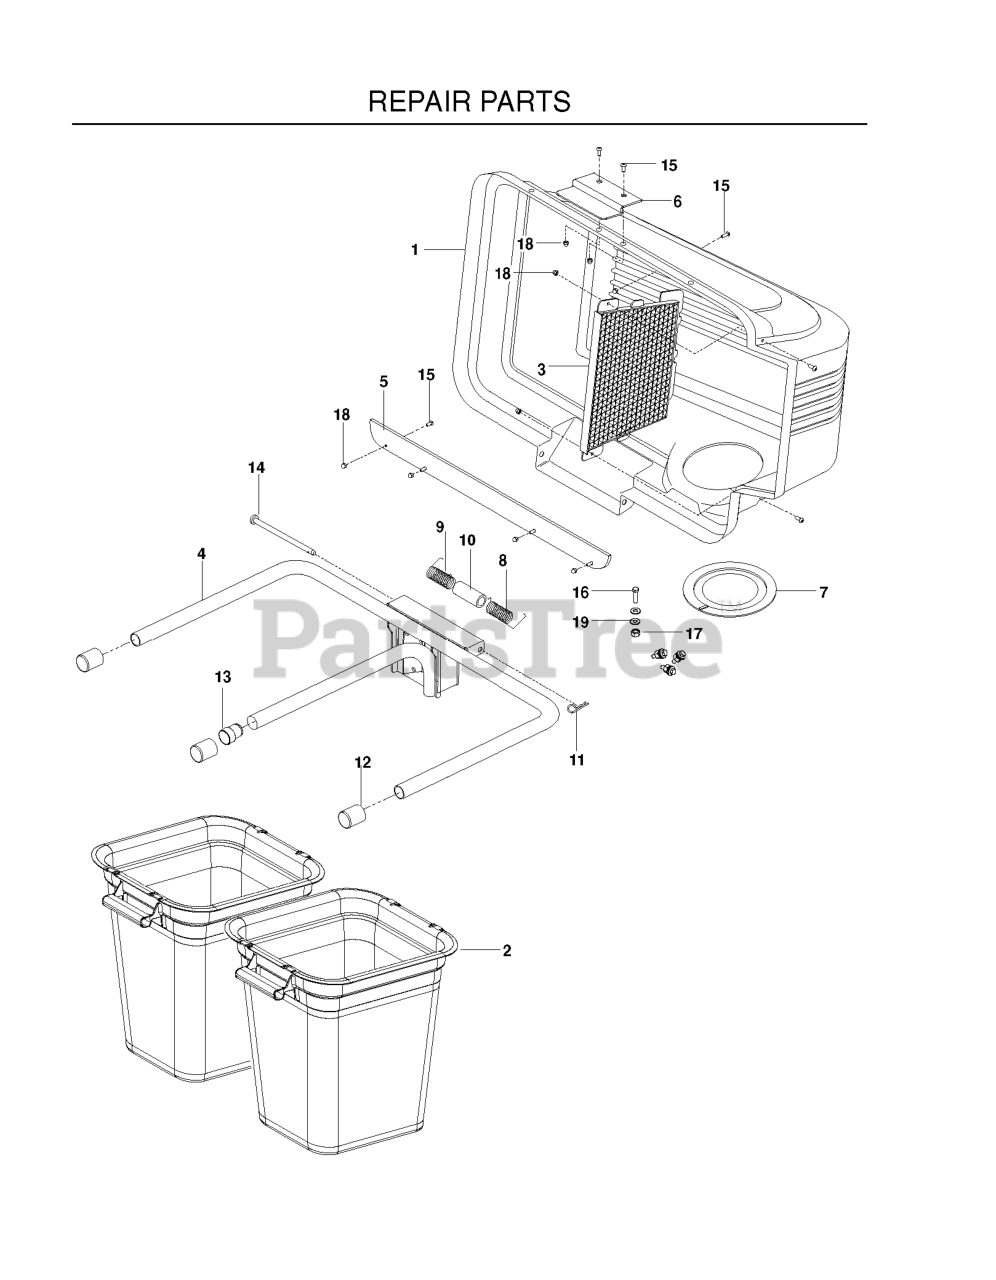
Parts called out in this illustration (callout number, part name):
2	CONTAINER BAG, SOFT
3	COVER SCREEN
4	FRAME.ASM.BAGGER.2BIN.QC42B
5	STRIP.REINFORCE.BAGGER.2BIN.BL
6	LATCH CER38
7	GASKET.COVER.BAGGER
8	SPRING COVER LH
9	SPRING COVER RH
10	SPACER.COVER.BAGGER
11	RETAINER SPRING
12	TUBING PLUG
13	SPACER PLUG, BAGGER
14	BAGGER.HINGE.PIN
15	SCREW #10-24 X 5/8
16	SCREW 10-24 X 3/4
17	NUT 10-24 NYLOC
18	NUT 10-24 ACORN ZD
19	WASHER #10
